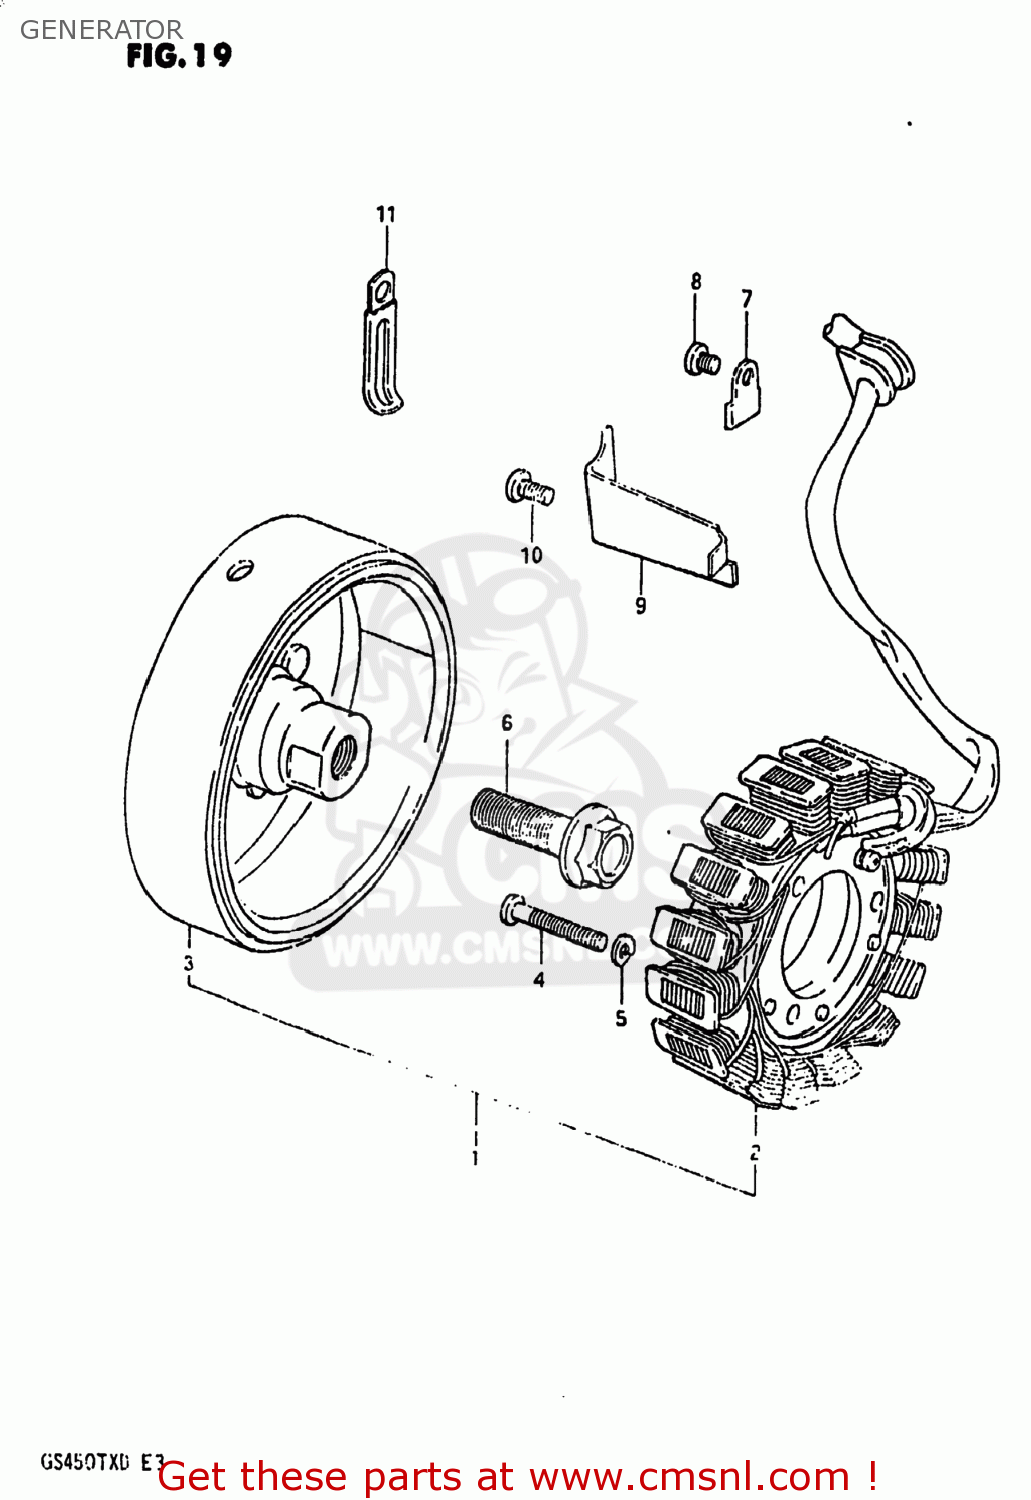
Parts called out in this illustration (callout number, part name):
1	GENERATOR ASSEMBLY
2	STATOR ASSEMBLY
3	ROTOR ASSEMBLY
4	SCREW
5	LOCK WASHER
6	BOLT(12X40)
7	CLAMP,GENERATOR LEAD WIRE
8	SCREW
9	CLAMP,GENERATOR LEAD WIRE
10	SCREW
11	CLAMP L:35
